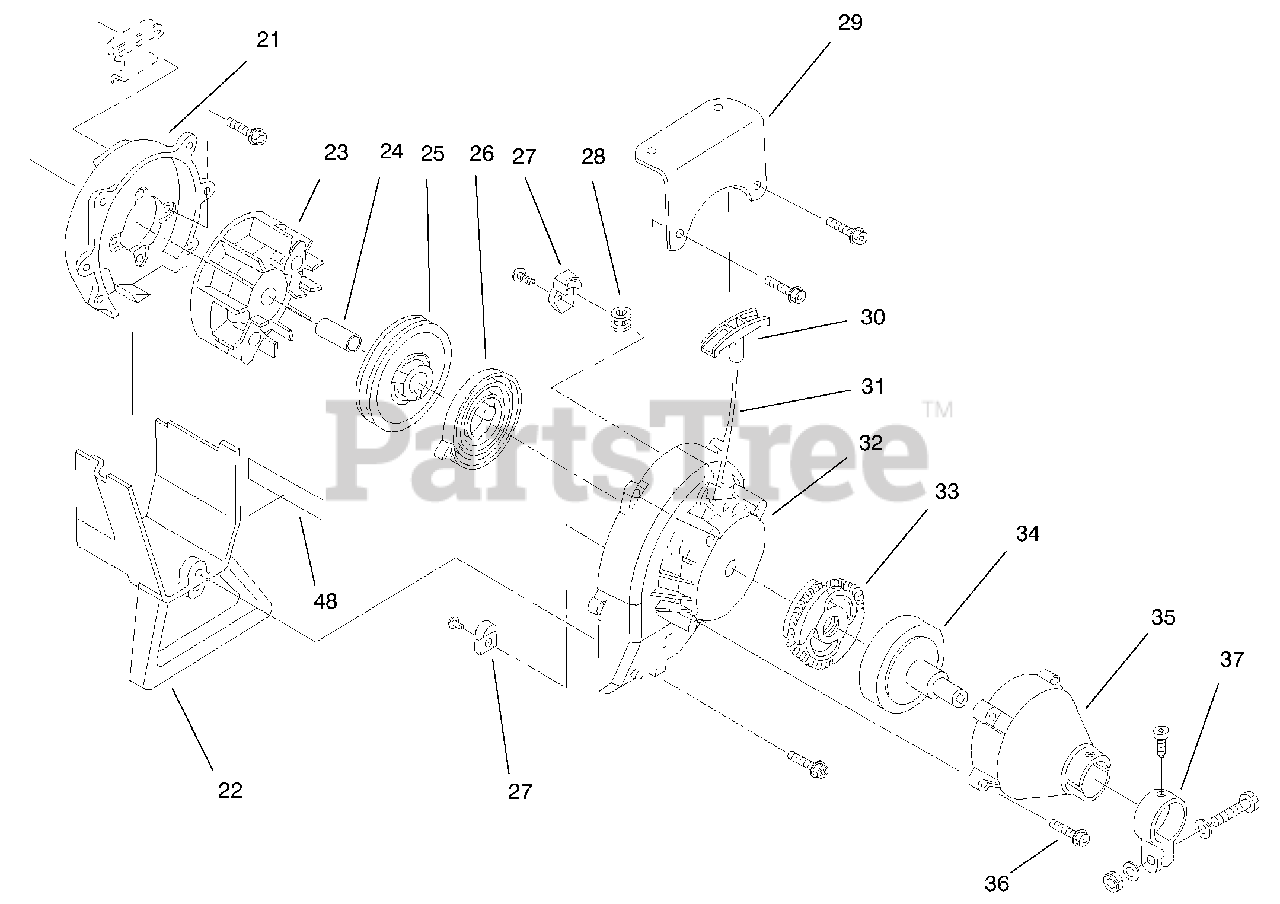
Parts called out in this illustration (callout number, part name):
21	Shroud Asm
22	Shroud Extension & Stand
23	Flywheel Asm.
25	Recoil Pulley Asm.
26	Recoil Spring
27	Pulley Retainer Asm.
28	Rope Guide
29	Fuel Tank Guard Asm.
30	Pull Handle
32	Starter Housing Asm.
33	Clutch Rotor Asm.
34	Clutch Drum Asm.
35	Clutch Cover Asm.
36	Clutch Cover Screw Asm.
37	Upper Clamp Asm.
48	Decal-Warning
